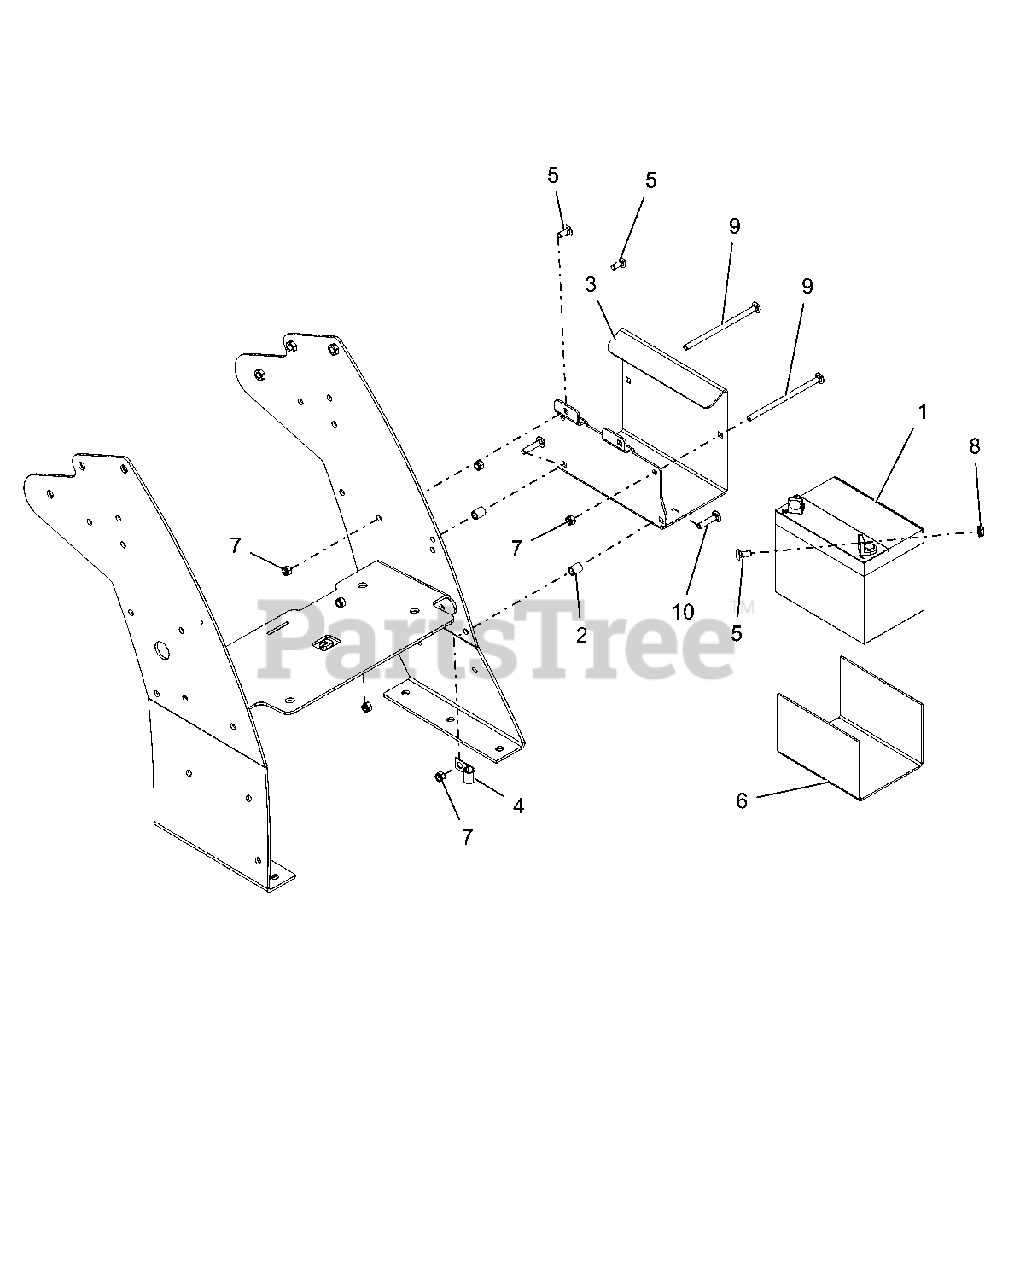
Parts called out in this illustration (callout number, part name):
1	BATTERY, 12V-U1-CCA270MIN
2	BUSHING, .364X.540X.700 Y
3	TRAY, BATTERY ELEC
4	P-CLIP, .500 INSULATED
5	BLT-RDHDSQNK .31-18X.75 G5 YWZC
6	STRIP, RUBBER
7	NUT-LK-NYL .312-18 YWZC
8	@NUT-SPNLK-FLG .312-18 YWZC
9	BLT-RDHDSQNK .31-18X6.00 G5 Y
10	BLT-RDHDSQNK .31-18X1.50 G5 YWZC
